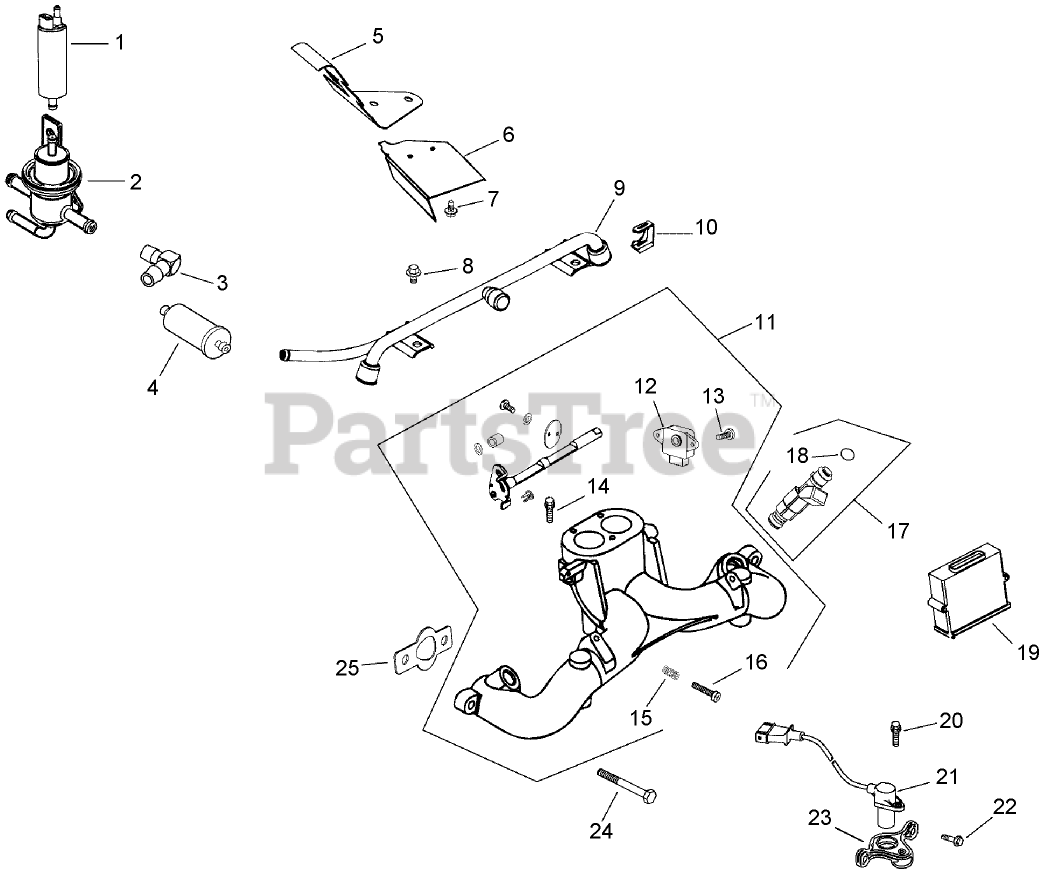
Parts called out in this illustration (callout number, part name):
1	Fuel Pump ASM (Includes 24 050 06-S)
2	Fuel Pressure Regulator ASM
3	Connector-Hose
4	Filter-Fuel
5	Baffle-Valley
6	Deflector-Air
7	SCREW-HHFTF (M5X.80X10)
8	Screw-HF (M6x1.0x10)
9	Rail-Fuel
10	Clip-Injector, Fuel
11	Intake Manifold ASM (Includes 18-22 and 25 454 03-S)
12	Sensor-Position,Throttle
13	Screw-Head, Pan
14	Screw-Set
15	Spring-Control, Speed
16	Screw-HH
17	Injector-Fuel (Includes 24)
18	O Ring-Injector, Fuel
19	Control Unit-Electronic (ECU)
20	Screw-HF
21	Sensor-Speed, Engine
22	SCREW-FLANGE, THREAD FORMING (M5X0.8X16)
23	Bracket-Sensor,Speed
24	Screw-HF
25	Gasket-Manifold, Intake
